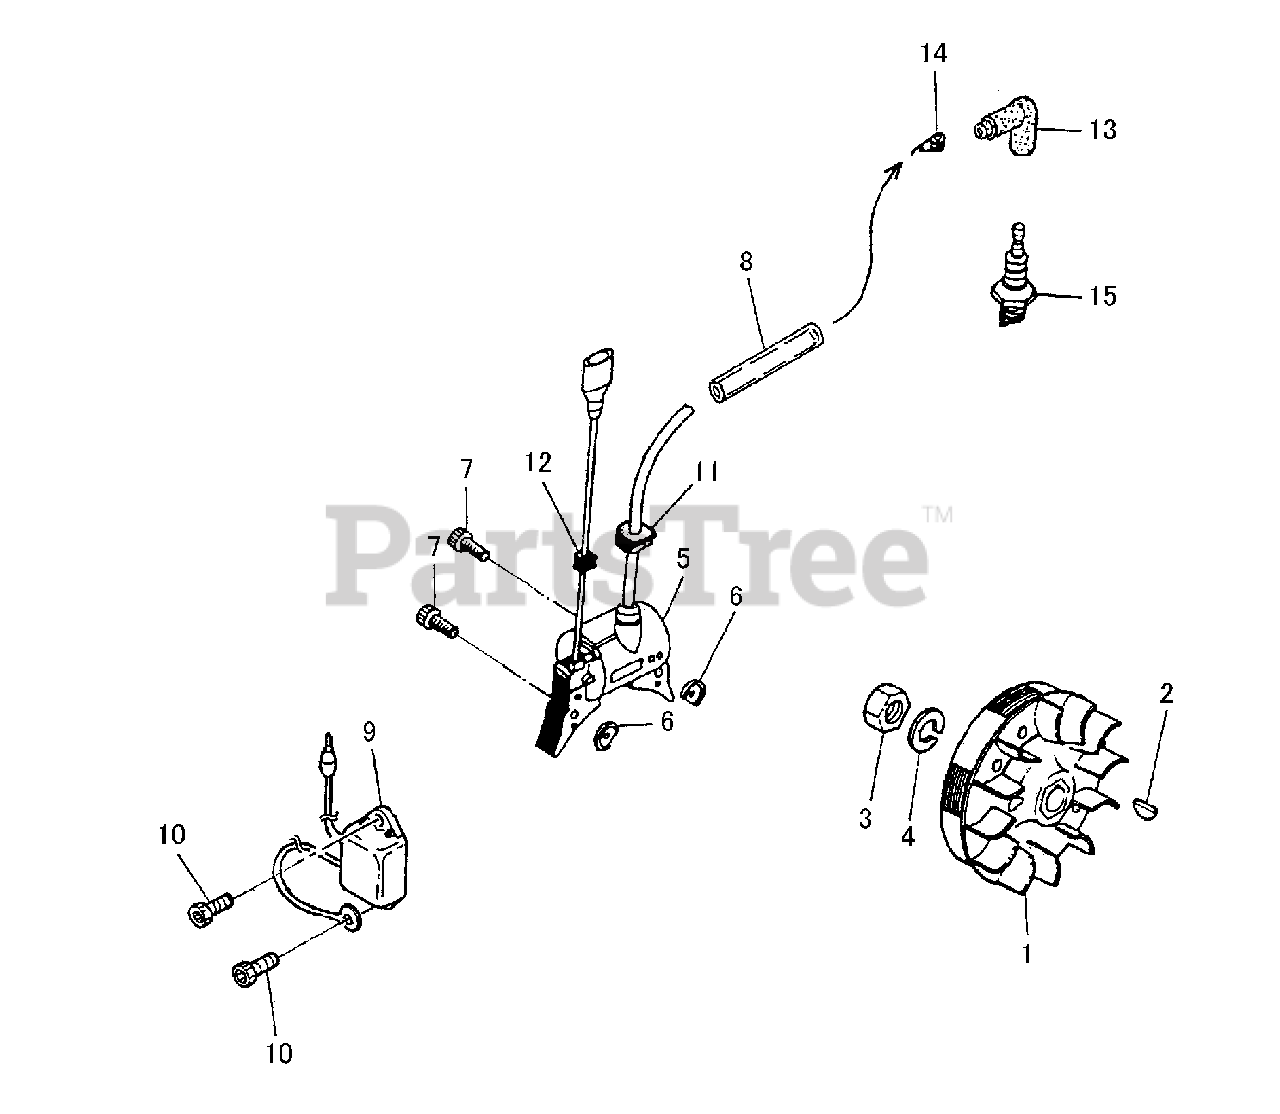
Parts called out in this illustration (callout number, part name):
1	FLYWHEEL
2	KEY - 3X10
3	NUT - 10
4	LOCKWASHER - 10
5	COIL, IGNITION
6	INSULATOR
7	SCREW - 4X26
8	TUBE
9	UNIT, ELECTRONIC
10	SCREW - 4X12
11	GROMMET
12	GROMMET
13	CAP, SPARK PLUG
14	TERMINAL, SPARK PLUG CAP
15	SPARK PLUG -- CJ8
